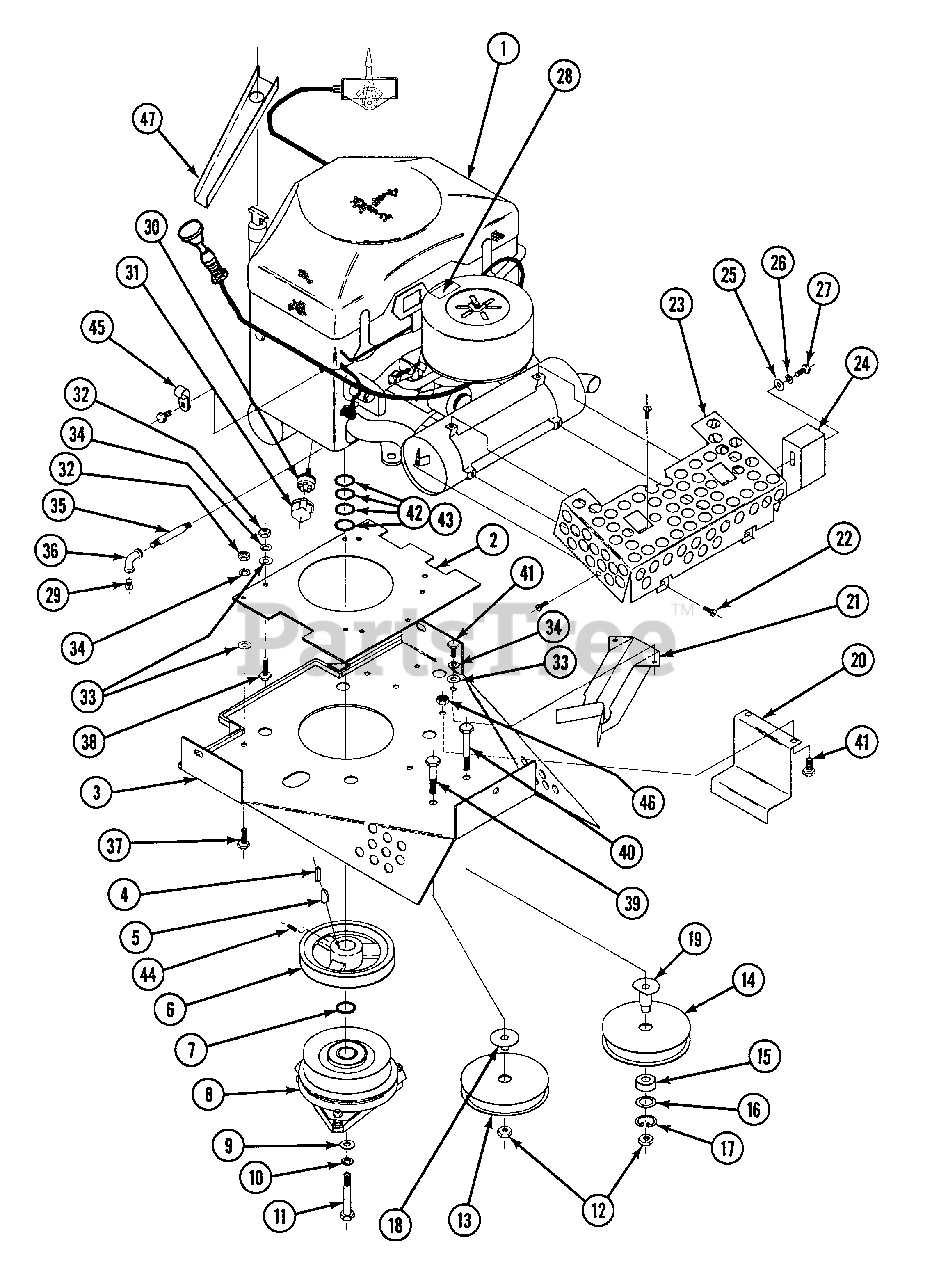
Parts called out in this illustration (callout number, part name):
1	* 18 HP KOHLER, VERICAL SHAFT ENGINE
1	* 20 HP KOHLER, VERICAL SHAFT ENGINE
2	MOTOR MOUNT PLATE
3	MOTOR MOUNT WELDMENT
4	KEY, 1/4 SQ. X 1 (18HP ENGINE)
5	KEY, WOODRUFF: 1/4 X 3/4 (20HP ENGINE)
6	PULLEY, 1" BORE (18 HP ENGINE)
6	PULLEY, 1-1/8" BORE (20 HP ENGINE)
7	WASHER, 1" I.D. X 1/8" THK
8	CLUTCH, ELECTRIC, 1" BORE
9	WASHER, 15/32 I.D.
10	LOCKWASHER, SPLT SPRNG: 7/16
11	CAPSCREW, HX HD: 7/16-20 X 3 GR. 5
12	LOCKNUT, NYLOCK: 1/2-13
13	IDLER ASSEMBLY, FLAT
14	FLAT IDLER 5" DIA.
15	BEARING, NO.6203-2RS
16	WASHER, SEAL
17	SNAP RING, 40 MM BORE
18	BUSHING, SHORT
19	BUSHING, LONG
20	CLUTCH STOP BRACKET (EARLY MODELS)
21	CLUTCH STOP BRACKET (LATE MODELS)
22	SCREW, SHEET METAL: NO.8 X 1/2
23	MUFFLER GUARD
24	DEFLECTOR WELDMENT
25	FLAT WASHER, 1/4
26	LOCKWASHER, SPLT SPRNG: 1/4
27	CAPSCREW, HX HD: 1/4-20 X 5/8 GR 5
28	DECAL, "PERIODICALLY CLEAN"
29	PLUG, PIPE: 3/8
30	SWITCH, OIL PRESSURE DUAL CIRCUIT
31	BOOT, OIL PRESSURE SWITCH
32	NUT, HEX: 5/16-24 GRADE 5
33	FLAT WASHER: 5/16
34	LOCKWASHER, SPLT SPRNG: 5/16
35	NIPPLE, 3/8 X 2-1/2 SCH. 40 BLACK
36	ELBOW, 3/8, 90D, SCH. 40 CAST IRON
37	CAPSCREW, HX HD: 5/16-24 X 1-1/2 GR 5
38	CAPSCREW, HX HD: 5/16-24 X 1 GR 5
39	CAPSCREW, HX HD: 1/2-13 X 2 GR 5
40	CAPSCREW, HX HD: 1/2-13 X 2-3/4 GR 5
41	CAPSCREW, HX HD: 5/16-18 X 3/4 GR 5
42	WASHER, 1" I.D. (18 HP ENGINE)
43	WASHER, 1-1/8" I.D. (20 HP ENGINE)
44	SETSCREW, SKT HD: 5/16-18 X 3/8
45	NYLON LOOP CLAMP, 1/2
46	LOCKNUT, NYLOCK: 5/16-18
47	OIL DEFLECTOR
